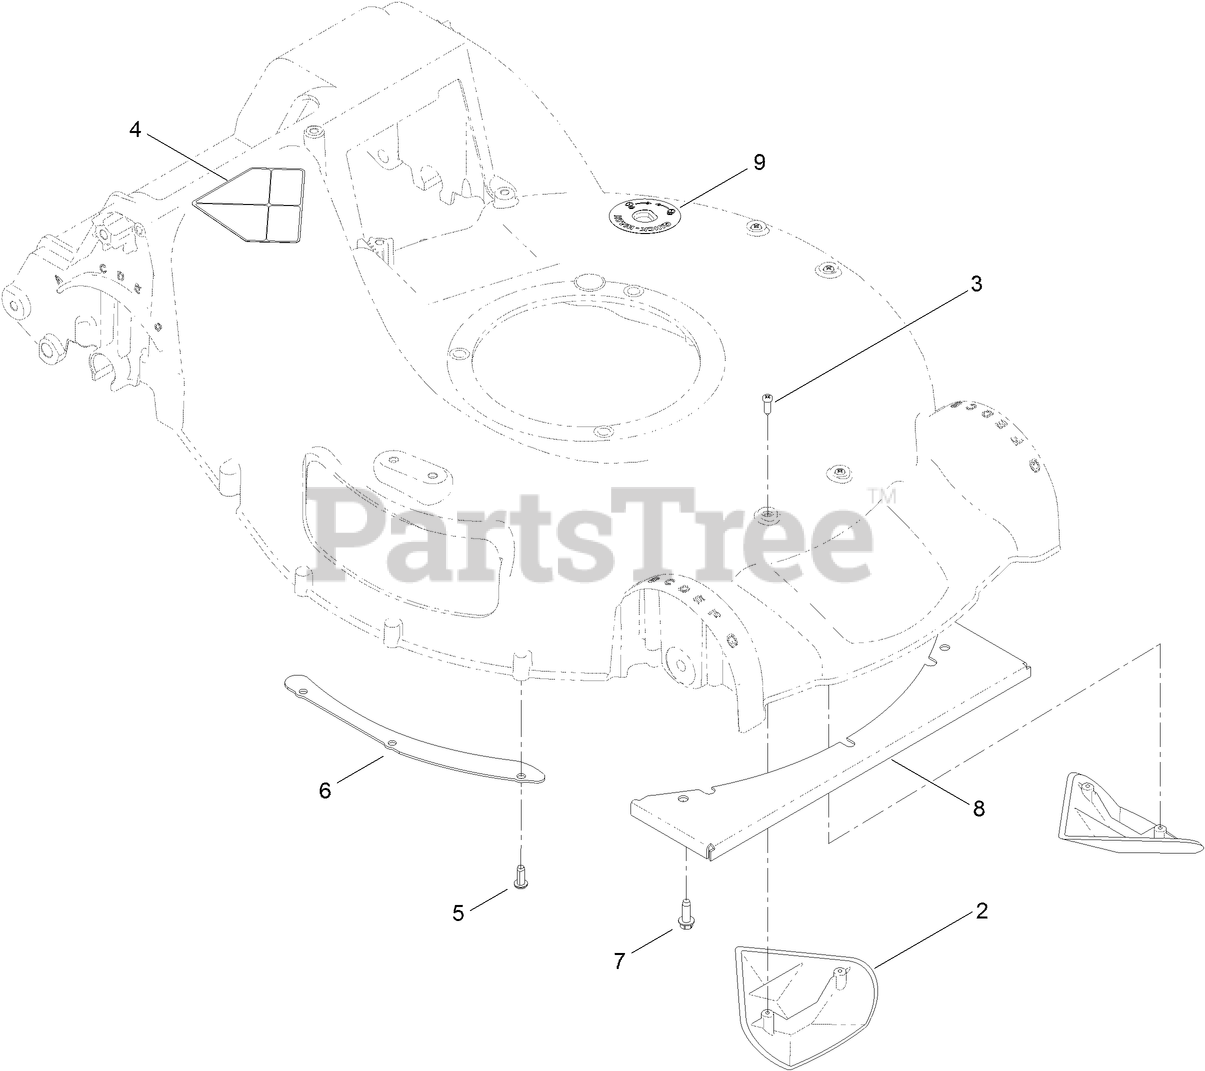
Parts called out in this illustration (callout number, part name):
2	KICKER-HOUSING
3	SCREW-PPH
4	DECAL-DANGER
5	SCREW
6	SHEET-LIP
7	SCREW-HWHTF
8	PLATE-COVER, FRONT
9	DECAL-PORT, WASHOUT
